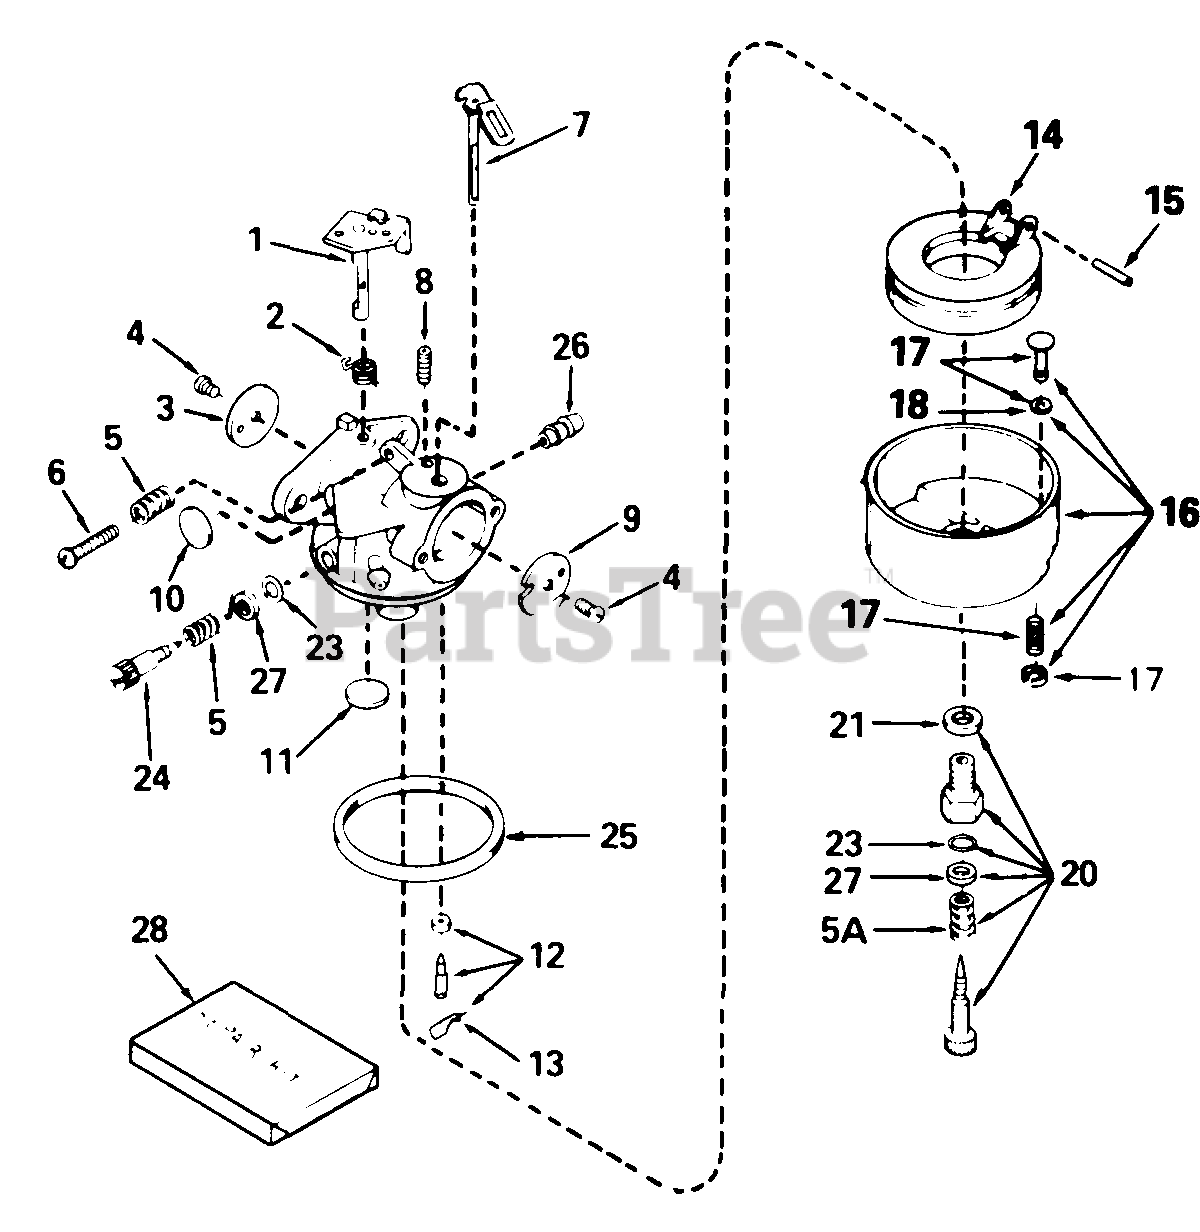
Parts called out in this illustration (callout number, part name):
1	Shaft & Lever Ass'y., Throttle
2	Spring, Throttle Return
3	Shutter, Throttle
4	Screw, Throttle & Choke Shutter
5	Spring, Regulating Screw
5A	Spring, Main Adjustment Screw
6	Screw, Idle Regulating
7	Shaft & Lever Ass'y., Choke
8	Spring, Choke Positioning
9	Shutter, Choke
10	Plug, Welch
11	Plug, Welch
12	Inlet Needle, Seat & Clip Ass'y.
13	Clip, Inlet Needle
14	Float, Carburetor
15	Shaft, Float
16	Bowl, Float
17	Plunger Ass'y., Drain
18	Gasket, Drain
20	Adjustment Screw Ass'y., Main
21	Gasket, Bowl-to-Body
23	"O"-Ring, Adjustment Screw
24	Screw, Idle Adjustment
25	Gasket, Bowl-to-Body
26	Fitting, Fuel Inlet
28	Repair Kit
